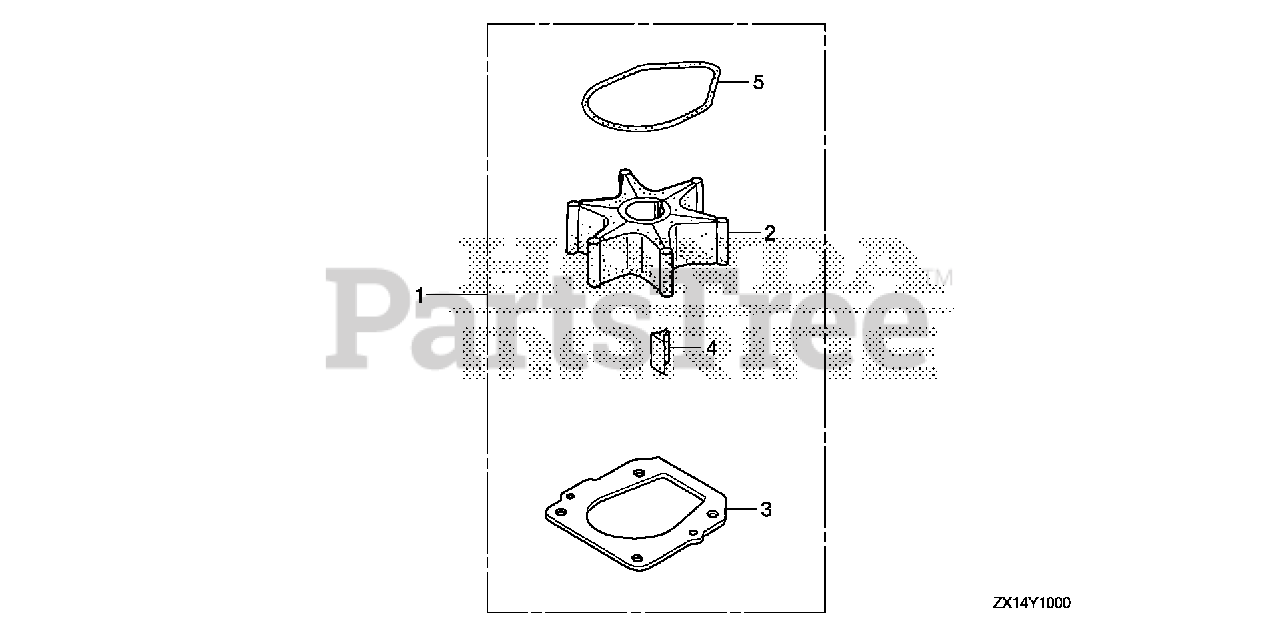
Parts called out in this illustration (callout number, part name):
1	PUMP KIT, IMPELLER
2	IMPELLER, PUMP
3	GASKET B, IMPELLER
4	KEY, WOODRUFF
5	O-RING, WATER PUMP
